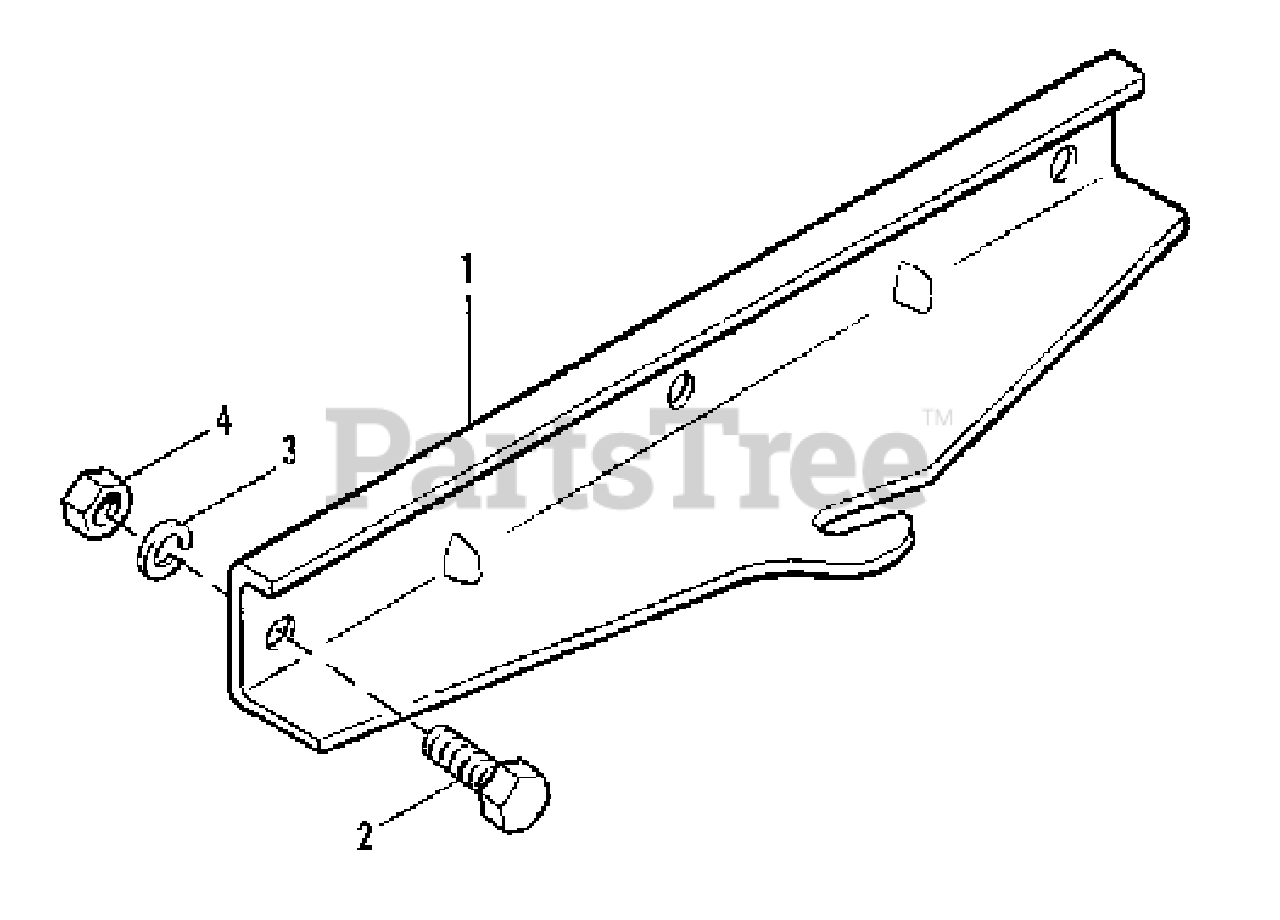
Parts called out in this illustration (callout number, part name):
1	SUPPORT, Attachment
2	CAPSCREW, Hex Head, 3/8-16 x 1
3	LOCKWASHER, 3/8
4	NUT, 3/8-16
